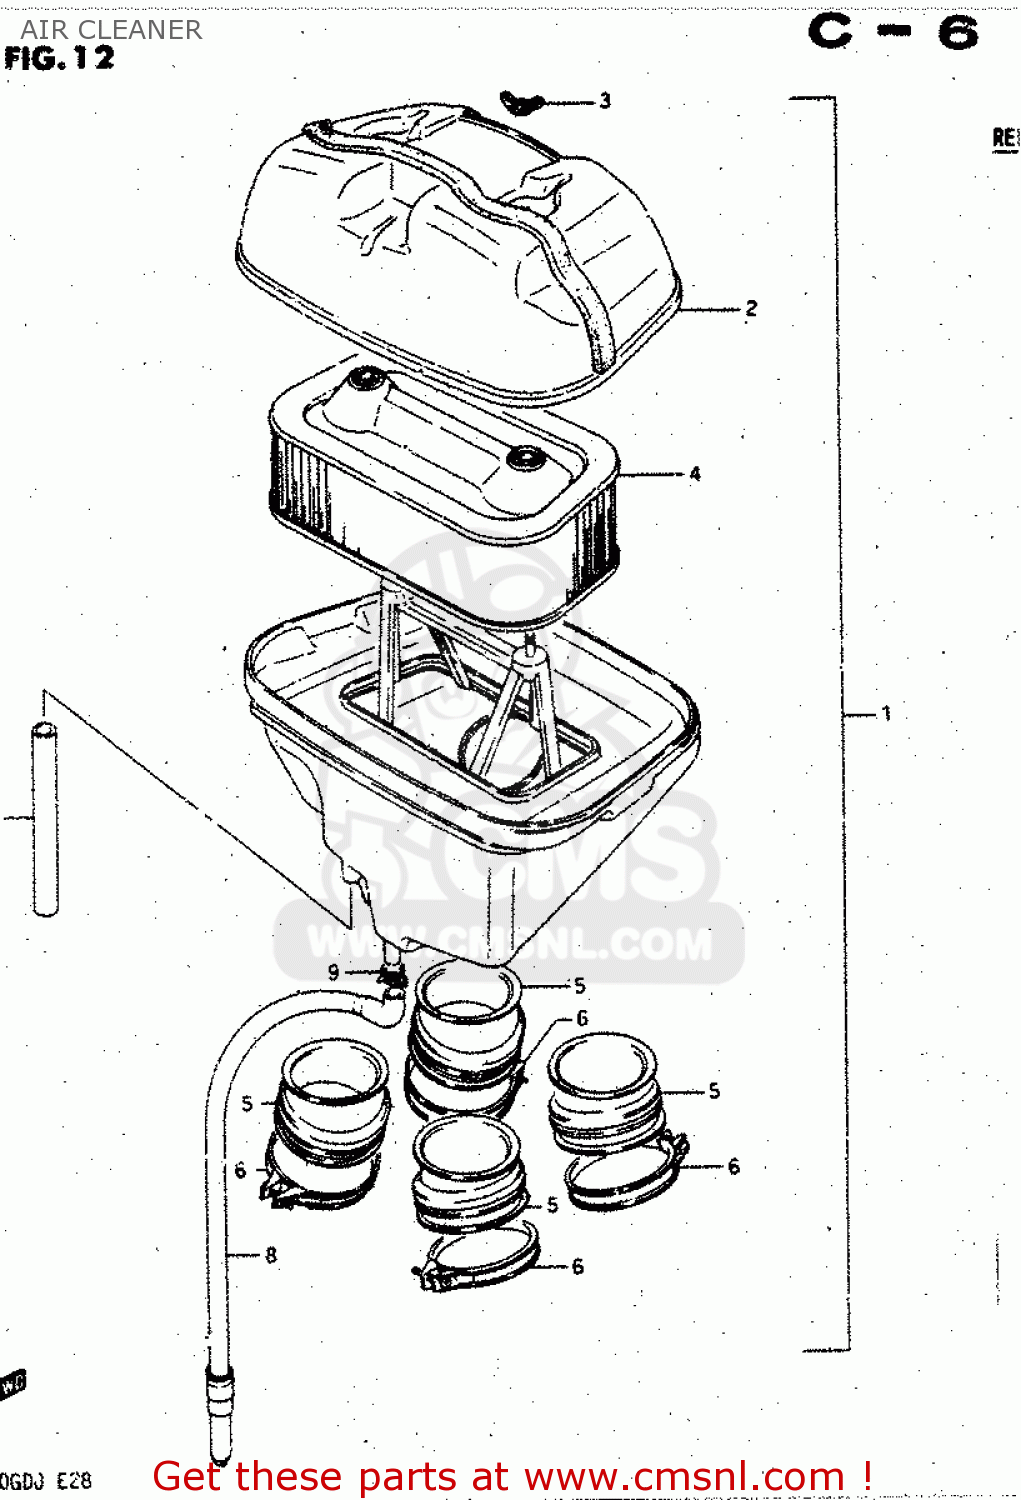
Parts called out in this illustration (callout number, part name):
1	CLEANER ASSEMBLY,AIR
2	CAP,AIR CLEANER
3	NUT, WING
4	FILTER ASSY
5	TUBE,AIR CLEANER OUTLET
6	CLAMP
7	TUBE,BREATHER
8	DRAIN TUBE
9	CLIP
